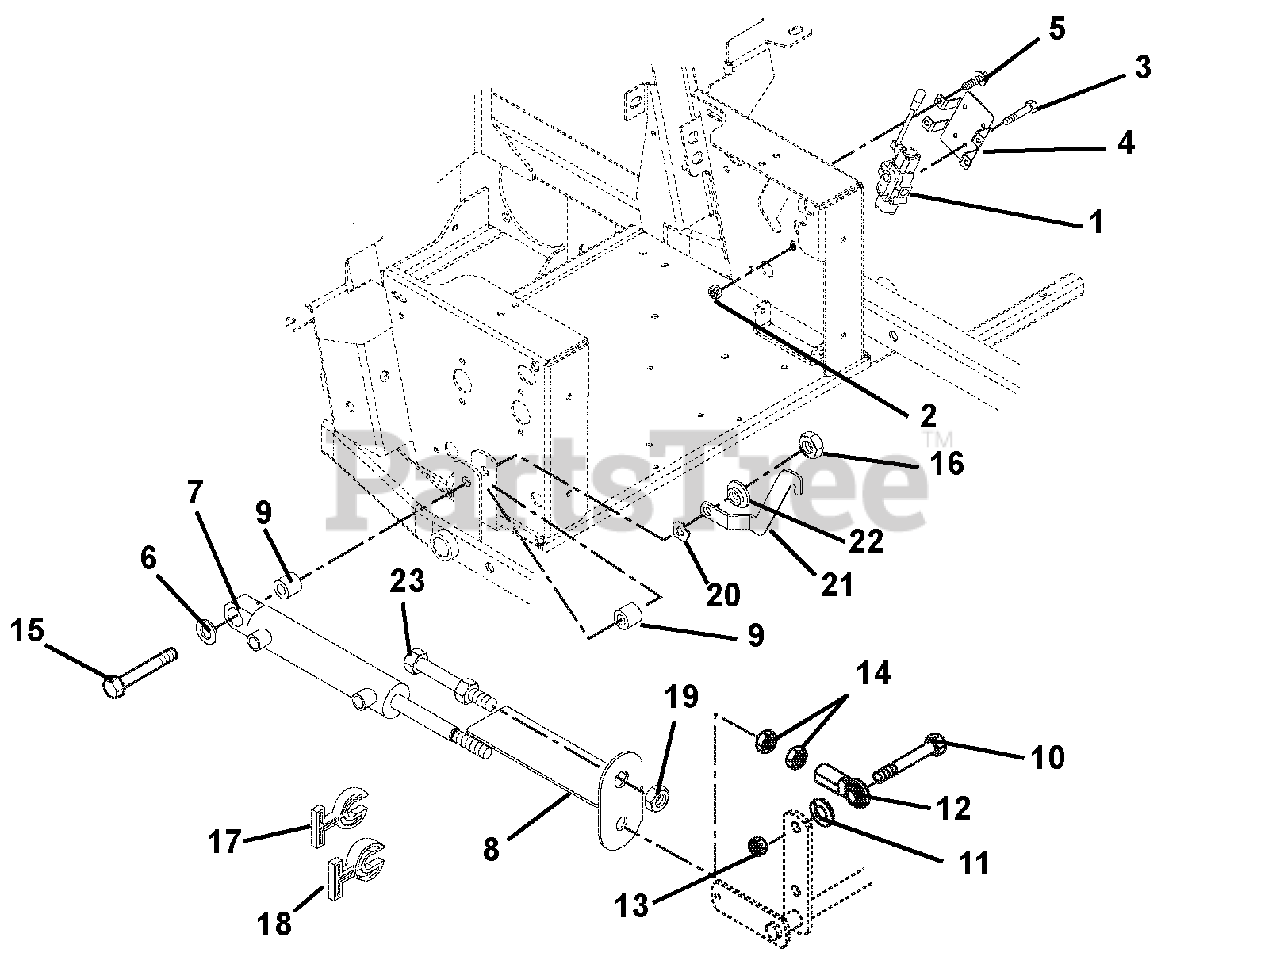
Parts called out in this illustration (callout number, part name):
1	Valve, Hydraulic
2	Nut, Locking Top Flange .31-18
3	Bolt, Hex .31-18 x 2.50 Grade 5
4	Bracket, Valve Mounting
5	Screw-Tapping .38-16 x .50 Hex Washer Head
6	Washer-Flat-Steel .515 x 1.625 x .25
7	Cylinder-Lift
8	Strap-Height of Cut Indicator
9	Bushing .516 x 1.00 x 1.05
10	Bolt-Hex .62-11 x 2.25 Grade 8
11	Washer-Lock .62 x .156
12	Rod End-Right Hand-Female .625
13	Nut-Locking-Center .62-11
14	Nut-Jam .625-18
15	Bolt-Hex .50-13 x 3.75 Grade 5
16	Nut, Locking Top Flange .50-13
17	Stop, Cylinder .34 Thick
18	Stop, Cylinder .68 Thick
19	Nut, Jam .75-16
20	Washer, Wave .076 x 1.12 x .08
21	Latch, Floor Board
22	Bushing-Flange .515 x .75 x .275 x 1.12
